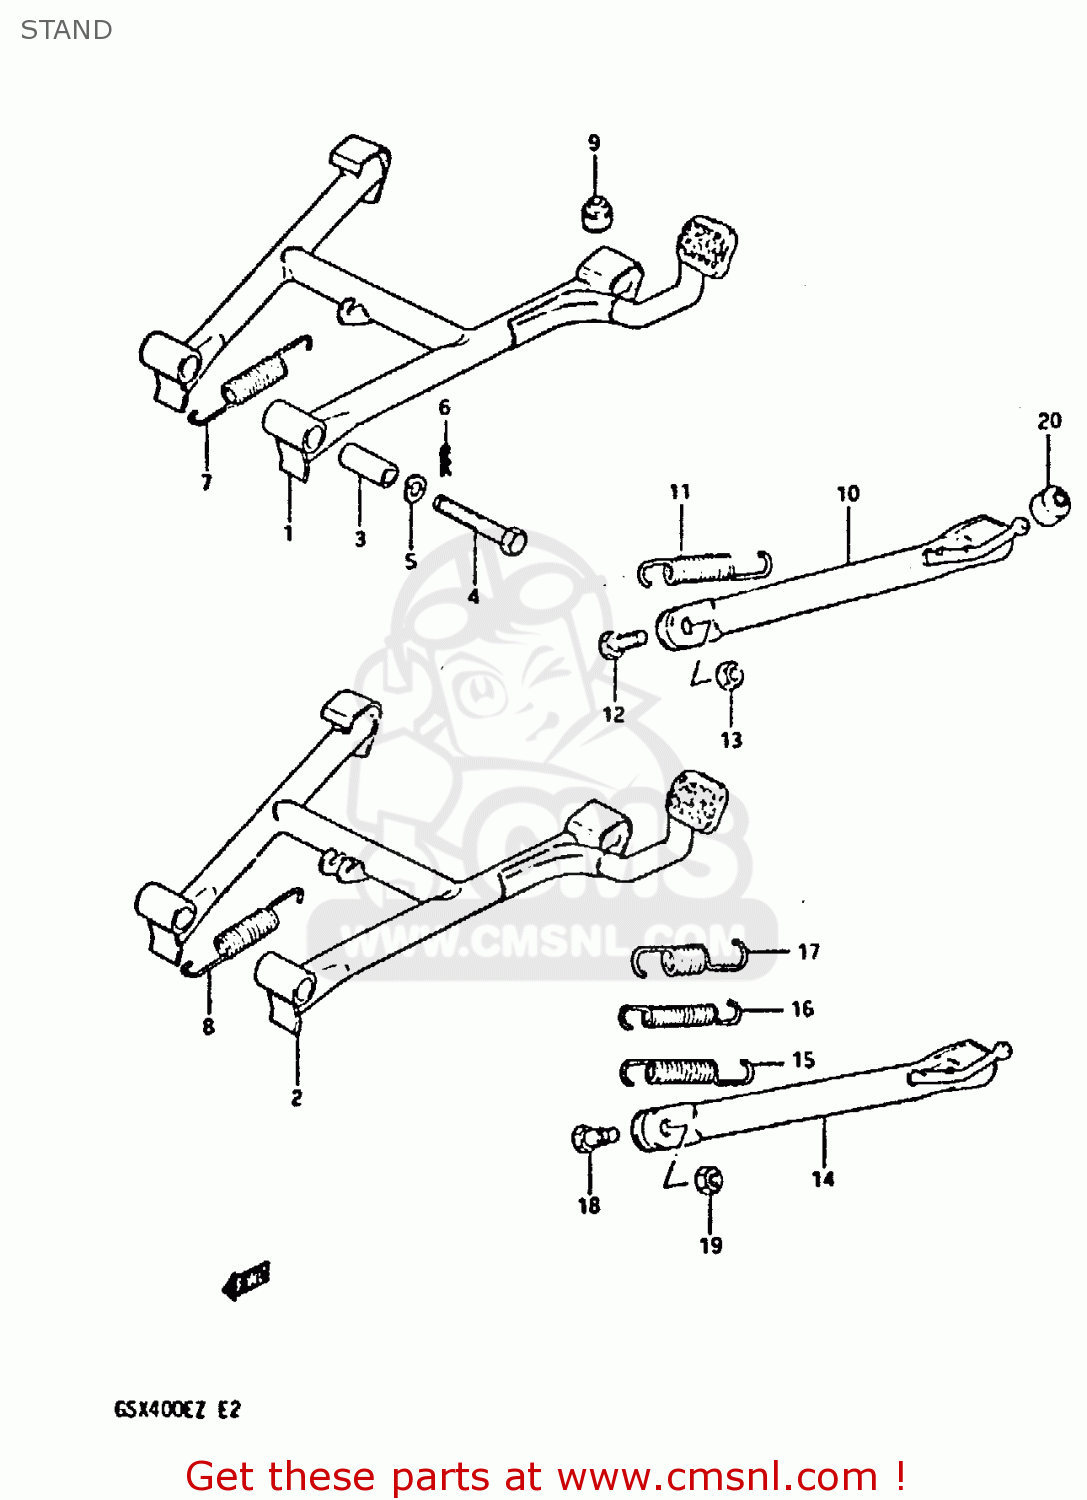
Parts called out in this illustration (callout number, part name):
1	STAND,CENTER
3	SPACER(10X16X38.8)
4	BOLT
5	LOCK WASHER
6	CLIP
7	SPRING
9	CUSHION
10	STAND,SIDE
11	SPRING
12	BOLT(10X30)
13	NUT
20	CUSHION
